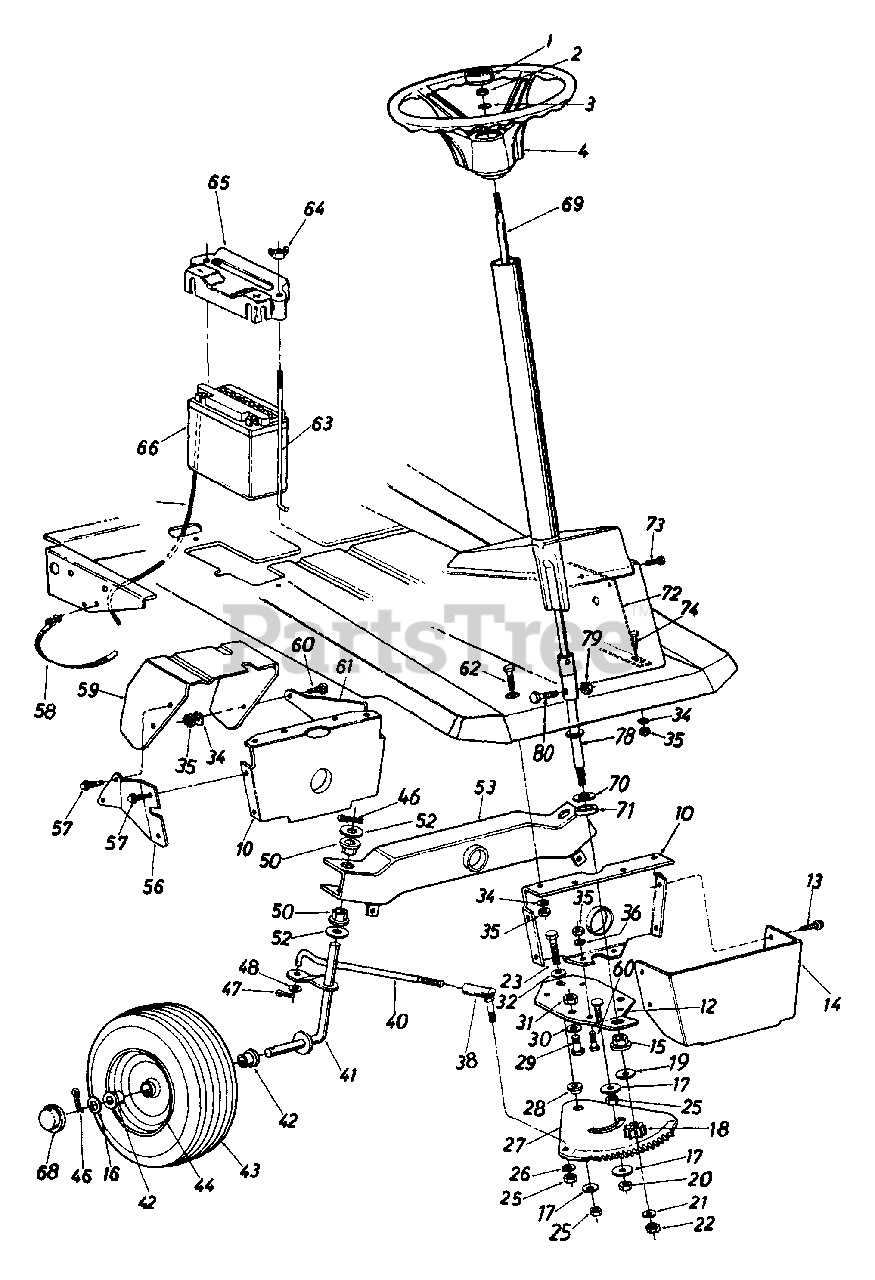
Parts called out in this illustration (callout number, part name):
1	Steering Wheel Cap
2	Hex L-Nut 5/16-24 Thd.
3	Bell-Wash. .345" I.D. x .88" O.D.
4	Steering Wheel Ass'y.
13	Hex Wash. Hd. AB-Tap Scr. 1/4 x .62" Lg.
16	Fl-Wash. .64" I.D. x 1.5" O.D.
17	Fl-Wash. 3/8" I.D. x 1.37" O.D.
18	Steering Pinion Gear
19	Fl-Wash. .51" I.D. x 1" O.D.
20	Hex L-Nut 3/8-24
21	Fl-Wash. .34" I.D. x .68" O.D.
22	Hex L-Nut 5/16-24 Thd.
23	Hex Bolt 3/8-24 x 1.5" Lg. (Grade 5)
25	Hex Nut 3/8-24 Thd.
26	L-Wash. 3/8" I.D.
27	Steering Gear Segment
28	Shoulder Spacer .622" Dia. x .218
29	Hex Bolt (Nylon) 1/2-13 x .75"
30	Fl-Wash. .530" I.D. x .930"
31	Hex Nut 1/2-13 Hd.
32	Bell-Wash. .385" I.D. x .88"
34	L-Wash. 5/16" I.D.
35	Hex Nut 5/16-18 Thd.
36	Spr. Wash. .32" I.D. x .62" O.D.
38	Ball Joint Ass'y. 3/8-24 Thd.
40	Steering Tie Rod
41	Front Axle Ass'y. - R.H.
42	Flange Bearing .632" I.D.
43	Front Wheel Ass'y. Comp.
44	Front Wheel Rim Only
46	Cotter Pin 1/8" Dia. x 1.25"
47	Cotter Pin 1/8" Dia. x 1.00"
48	Fl-Wash. .385" I.D. x .87"
50	Hex Flange Bearing
52	Fl-Wash. .635" I.D. x 1.12"
53	Pivot Bar Ass'y.
58	Cable Tie
59	Clutch-Brake Pedal Ass'y.
60	Hex Bolt 5/16-18 x .75" Lg.
63	Battery Hold Down Rod
64	Wing Nut Solid 1/4-20 Thd.
65	Battery Hold Down Cover
66	12V Battery
68	Hub Cap
69	Steering Shaft Ass'y.
70	Fl-Wash. .62" I.D. x 1.25" O.D.
71	Spacer (Plastic)
74	Hex Bolt 5/16-18 x 2.00" Lg.
78	Steering End Adapter
79	Hex Nylon L-Nut 1/4-20 Thd.
80	Hex Bolt 1/4-20 x 1.31" Lg.
